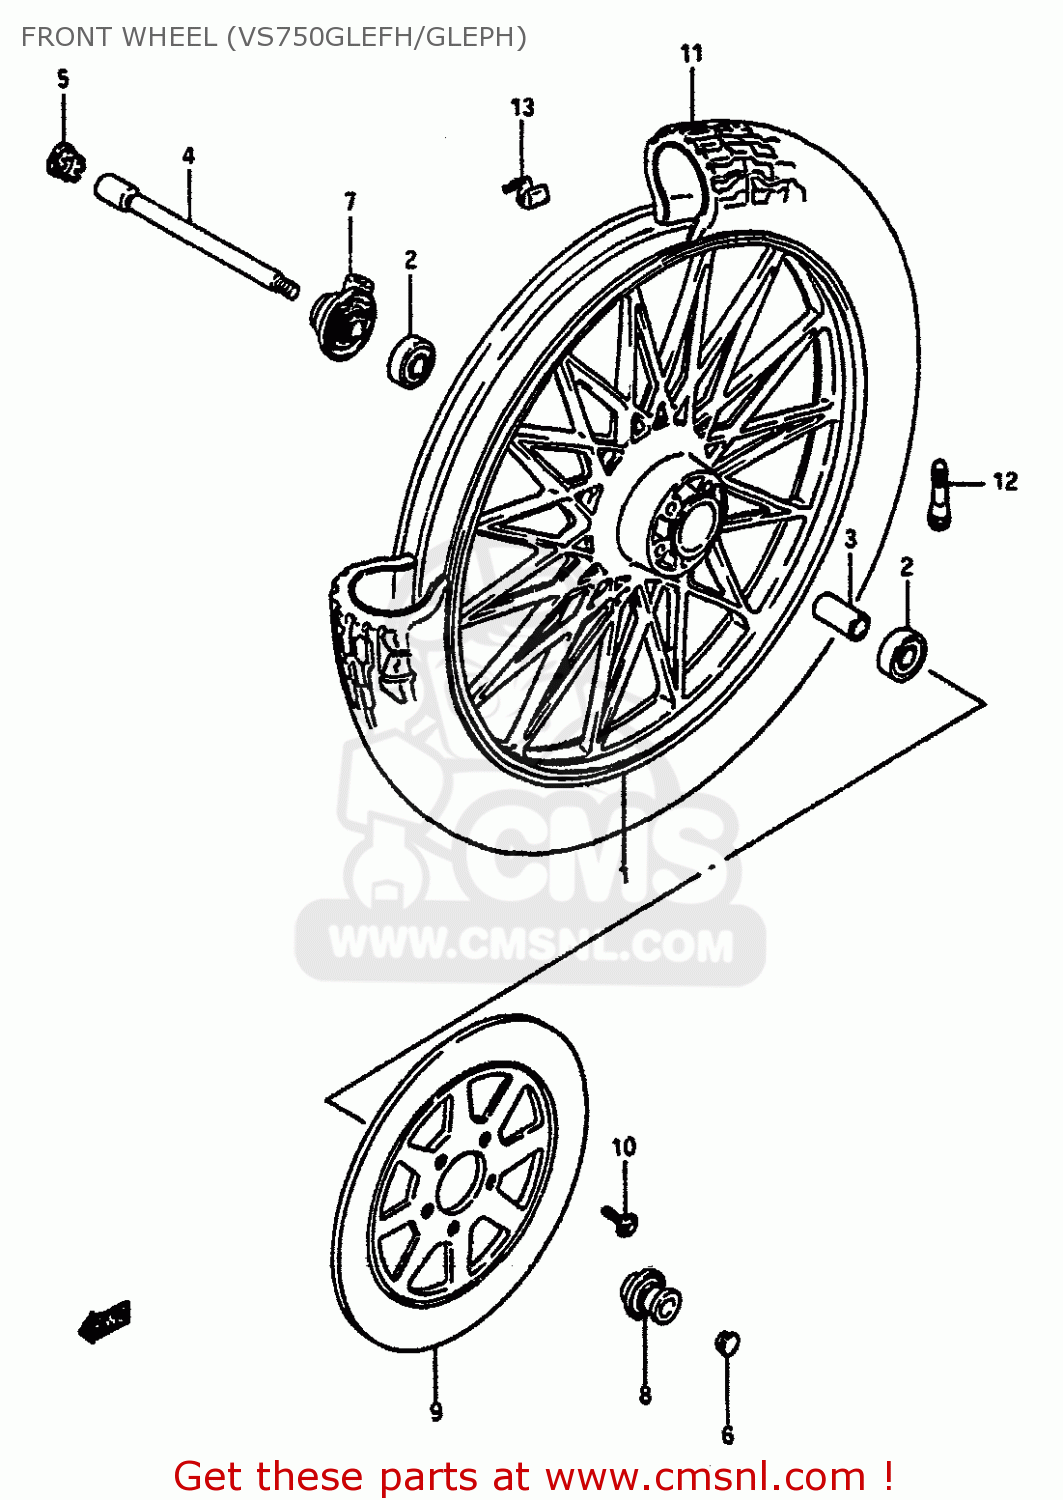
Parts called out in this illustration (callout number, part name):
1	CASTING WHEEL,FRONT 2.15-
2	BEARING
3	SPACER(15.3X21.7X65)
4	AXLE,FRONT
5	CAP,FR AXLE
6	CAP,FR AXLE
7	BOX ASSY,SPEEDOMETER GEAR
8	SPACER COMP,FRONT AXLE
9	DISC,FRONT BRAKE
10	BOLT(8X25.5)
11	TIRE,FRONT
12	VALVE,TIRE
13	BALANCER,WHEEL
